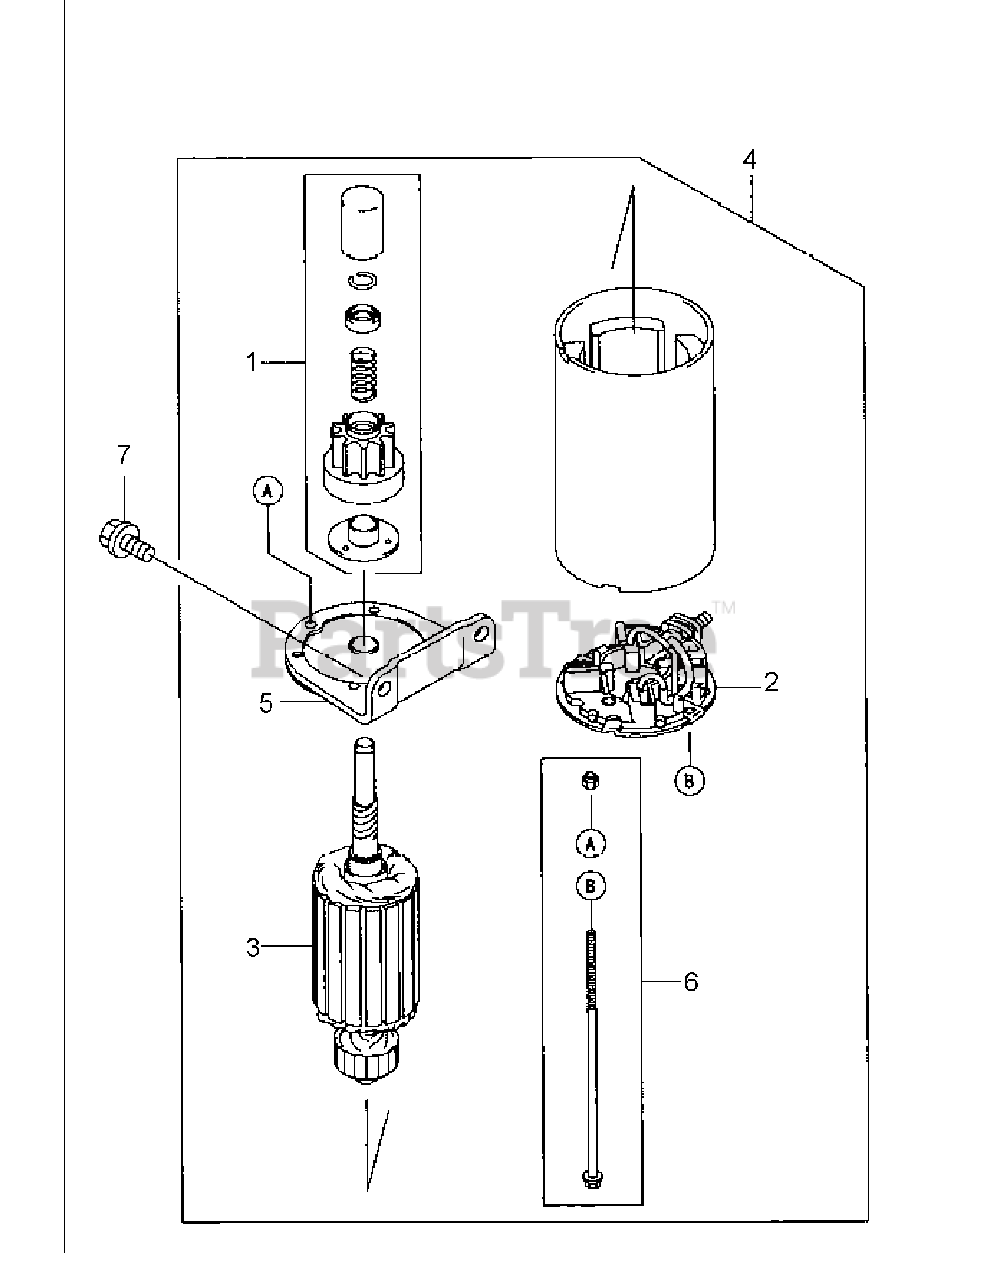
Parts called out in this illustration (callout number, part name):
1	GEAR ASSY.
4	ELECTRIC STARTER
5	BRACKET ASSY.
7	FLANGED BOLT
